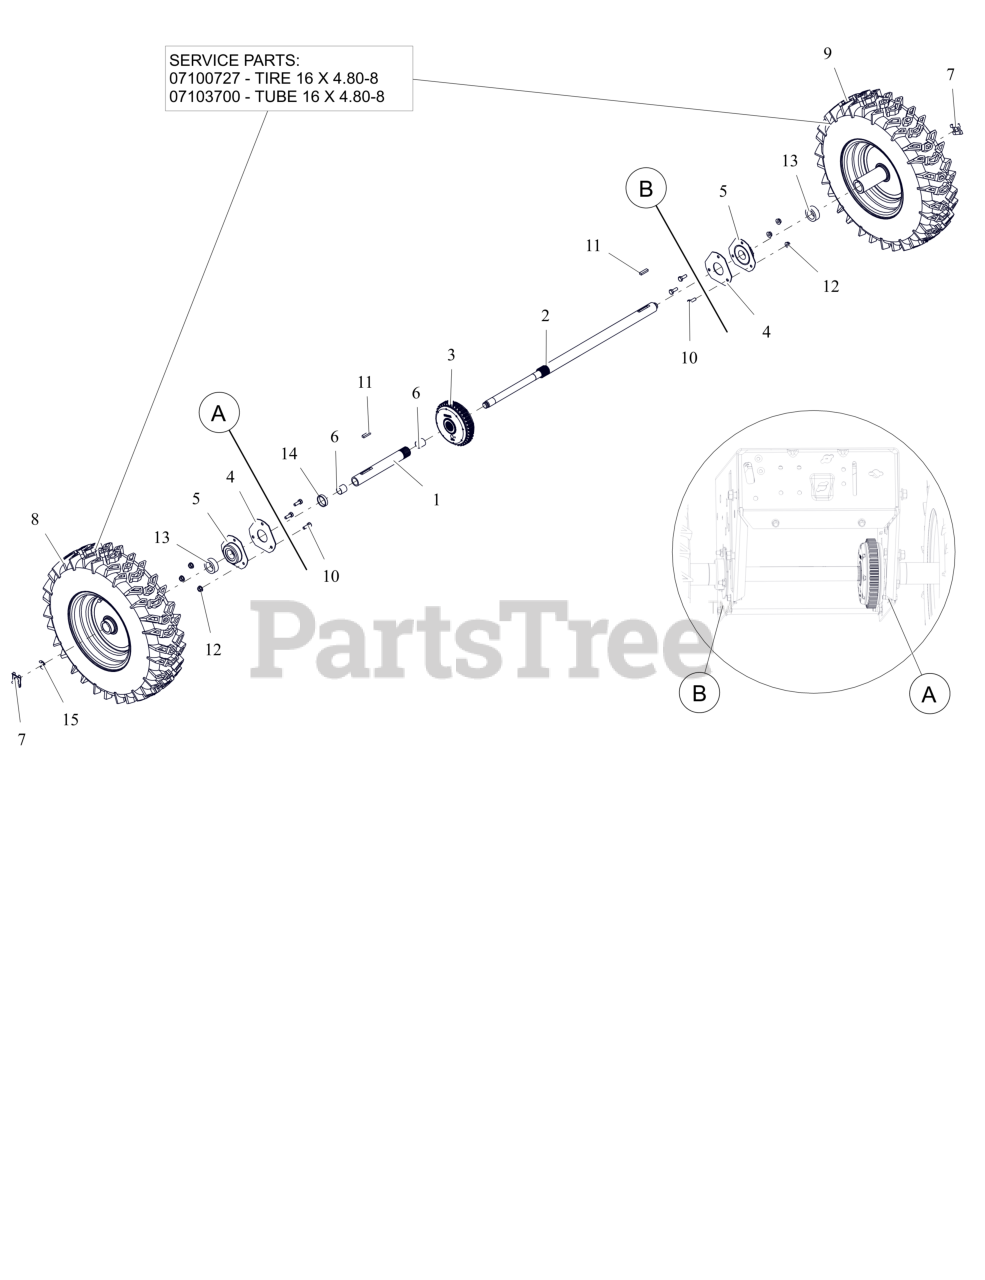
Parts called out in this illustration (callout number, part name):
1	AXLE, SHORT-AUTO W/BUSHINGS
2	AXLE, LONG-PRO AUTO DIFF
3	DIFFERENTIAL, AUTOMATIC
4	PLATE, BEARING SPACER
5	BRG-FLG 1.003/1.000 3 BOLT
6	BSHG-SLV .706X.764X.75 BRZ
7	CLIP, SNAP .625 DIA
8	TIRE/WHEEL RH 16X4.8-8 DIFF T2
8	SNOW TIRE, 16/4.80-8 K478 DIRECTIONAL
8	TIRE TUBE, 16X4.80/4.00-8 4 PLY TR13 STRAIGHT VALVE
9	TIRE/WHEEL LH 16X4.8-8 DIFF T2
9	SNOW TIRE, 16/4.80-8 K478 DIRECTIONAL
9	TIRE TUBE, 16X4.80/4.00-8 4 PLY TR13 STRAIGHT VALVE
10	BLT, HEX .25-20X.75 G5 ZCC
11	KEY-RECT .25X.188X1.00
12	NUT-LK-CTR-FLG .25-20 ZC120
13	SPACER, PRO AXLE BEARING
14	BSHG, SLV 1.062X1.228X.268
15	RG-RTNG-EXT .625X.042
